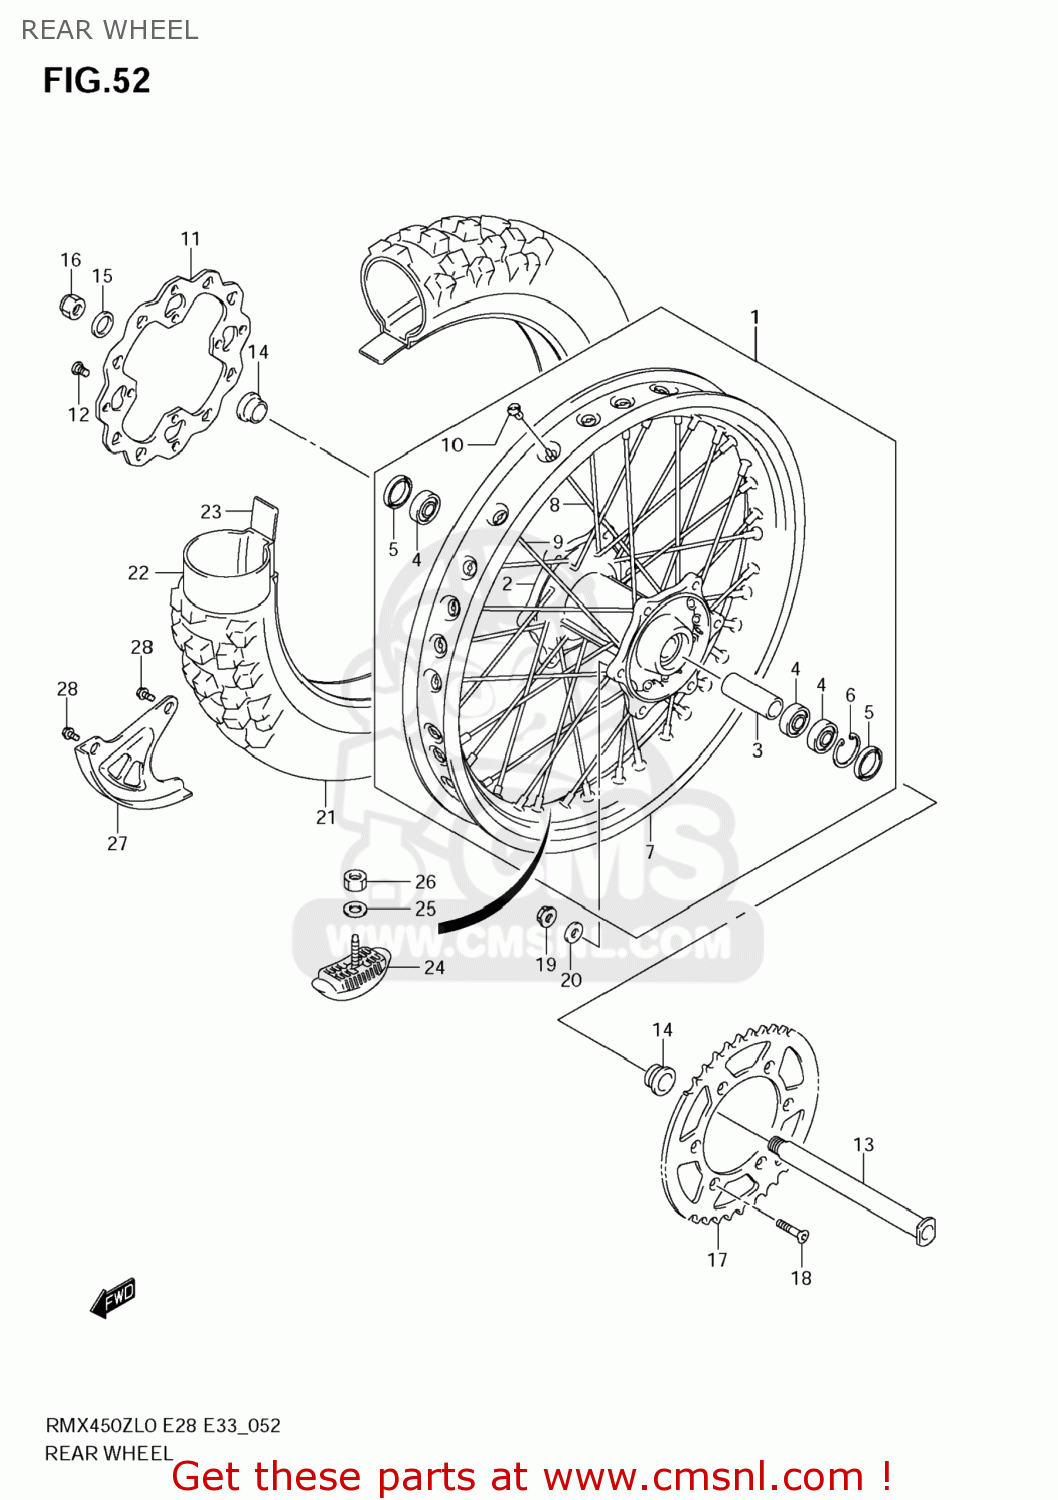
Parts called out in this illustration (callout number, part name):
1	WHEEL ASSY,RR
2	HUB,RR
3	SPACER,RR HUB BEARING
4	BEARING(25X42X9)
5	SEAL,OIL(32X43X7)
6	CIRCLIP
7	RIM,RR WHEEL(18X2.15 AL)(WHT)
8	SPOKE,RR WHEEL INNER
9	SPOKE,RR WHEEL OUTER
10	NIPPLE,RR WHEEL
11	DISC,RR BRAKE
12	SCREW(8X15)
13	AXLE,REAR
14	SPACER,REAR AX
15	WASHER(22X35X2)
16	NUT
17	SPROCKET,RR(51-520)
18	BOLT(8X28)
19	NUT
20	WASHER(8.5X16X1.2)
21	TIRE,RR(110/100 18 64M)
22	TUBE ASSY,WHEEL INNER
23	PROTECTOR,WHL INR TUBE
24	STOPPER,BEAD(2.15)
25	WASHER
26	NUT
27	COVER,REAR DIS
28	BOLT(6X12)
